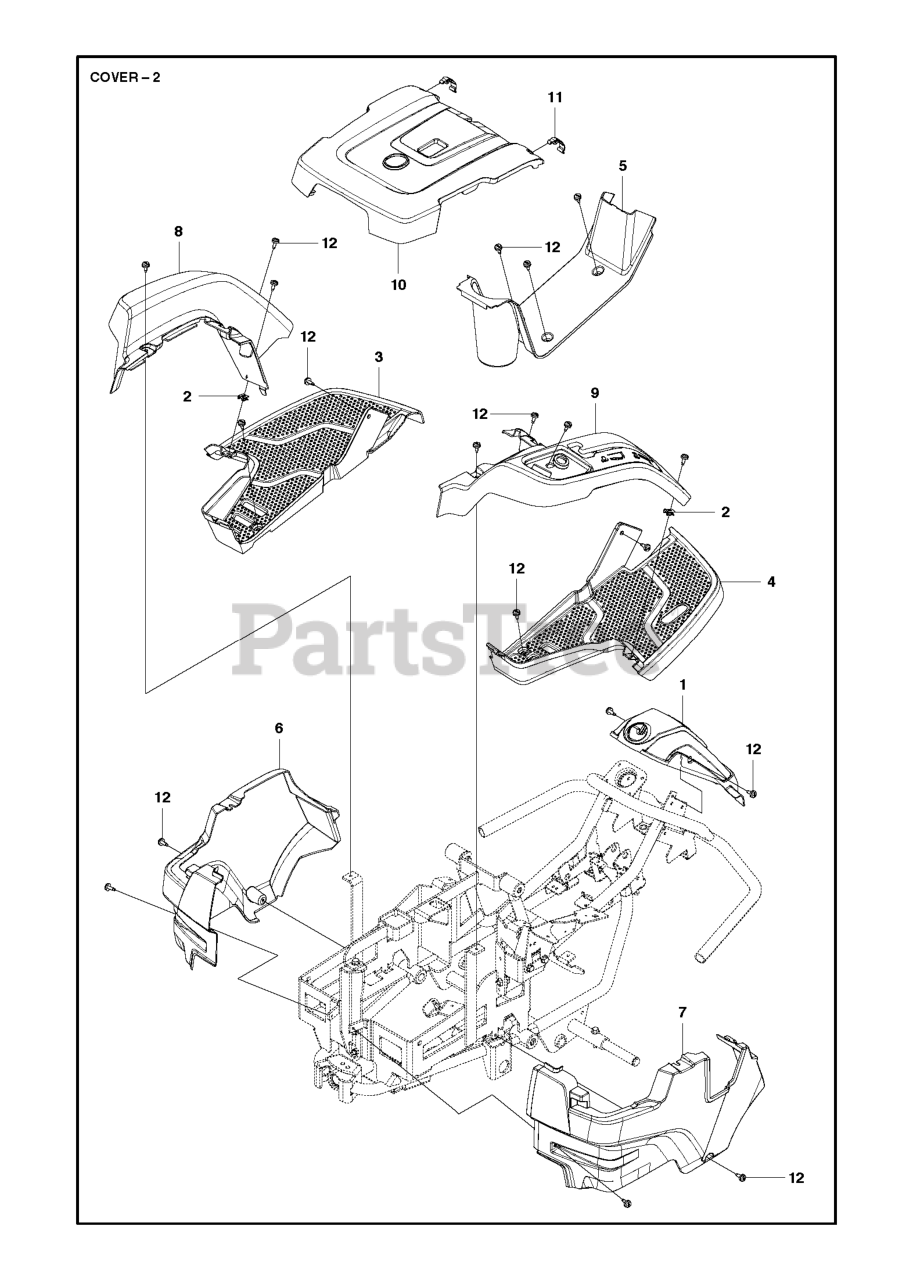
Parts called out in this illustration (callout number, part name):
3	FOOT PLATE
4	FOOT PLATE
11	CLIP GRAY
